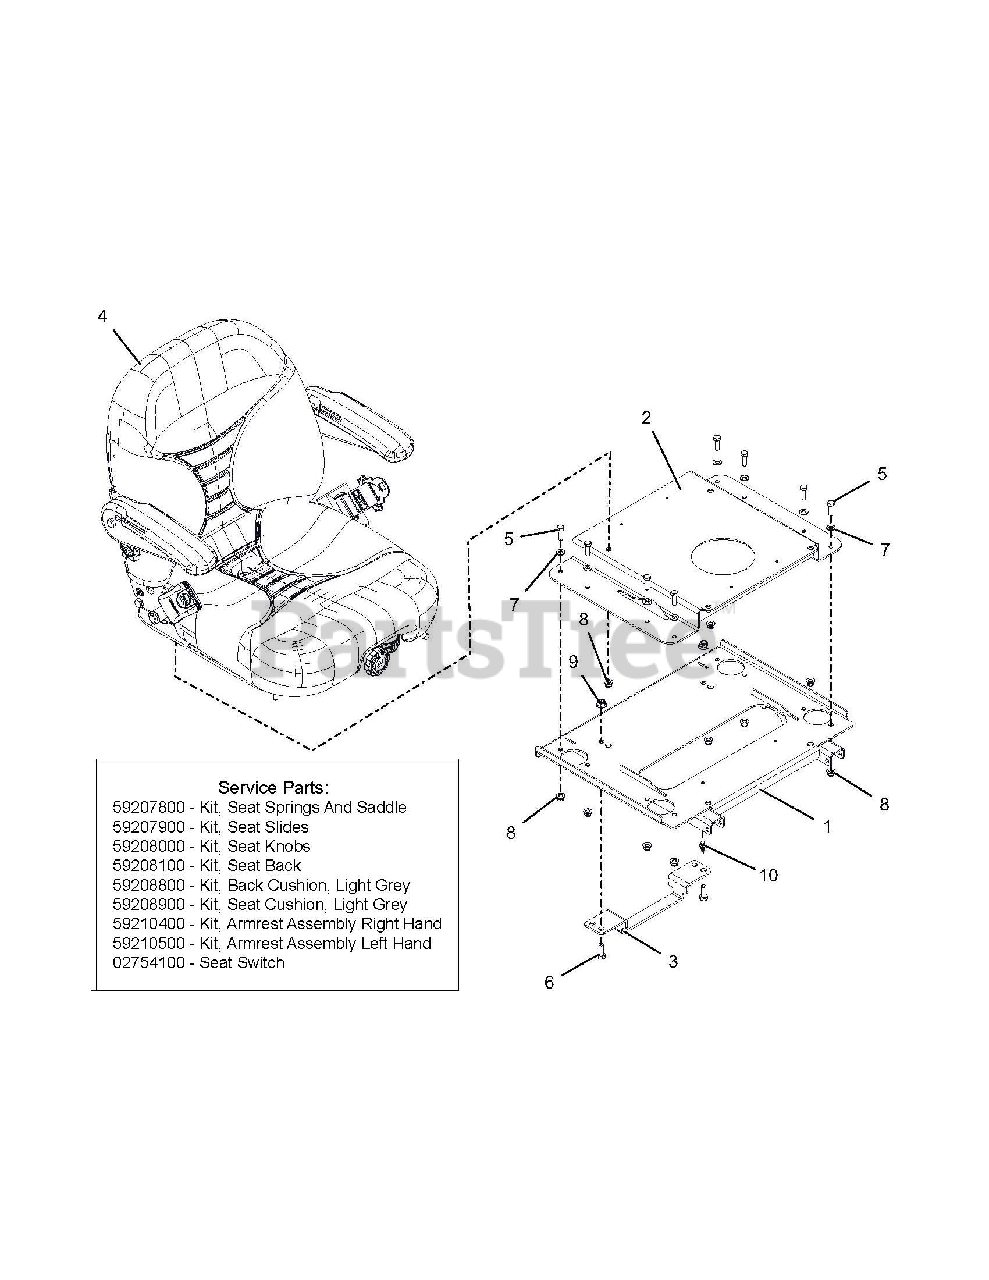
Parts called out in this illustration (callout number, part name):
1	SEAT ISO MTG WMT W/SAFETY DECALS
2	WLDMT, SEAT BASE MOUNTING-RED
3	BRKT, SEAT LATCH-BLACK
4	SEAT, SUSPENSION W/SEAT BELT, LT GRAY
4	KIT, SEAT SPRINGS AND SADDLE
4	KIT, SEAT SLIDES
4	KIT, SEAT KNOBS
4	KIT, SEAT BACK
4	KIT, BACK CUSHION, LIGHT GREY
4	KIT, SEAT CUSHION, LIGHT GREY
4	KIT, ARMREST ASSEMBLY RIGHT HAND
4	KIT, ARMREST ASSEMBLY LEFT HAND
4	SEAT SWITCH
5	BLT-HEX .31-18X1.00 GR5 YWZC
6	BLT-HEX .38-16X1.00 GR5 YWZC
7	WSHR-FL-STL.344X.688X.065YWZC
8	NUT-LK-NYL-FLG .31-18 YWZC
9	NUT-LK-NYL-FLG .38-16 YWZC
10	CABLE TIE W/ TREE
